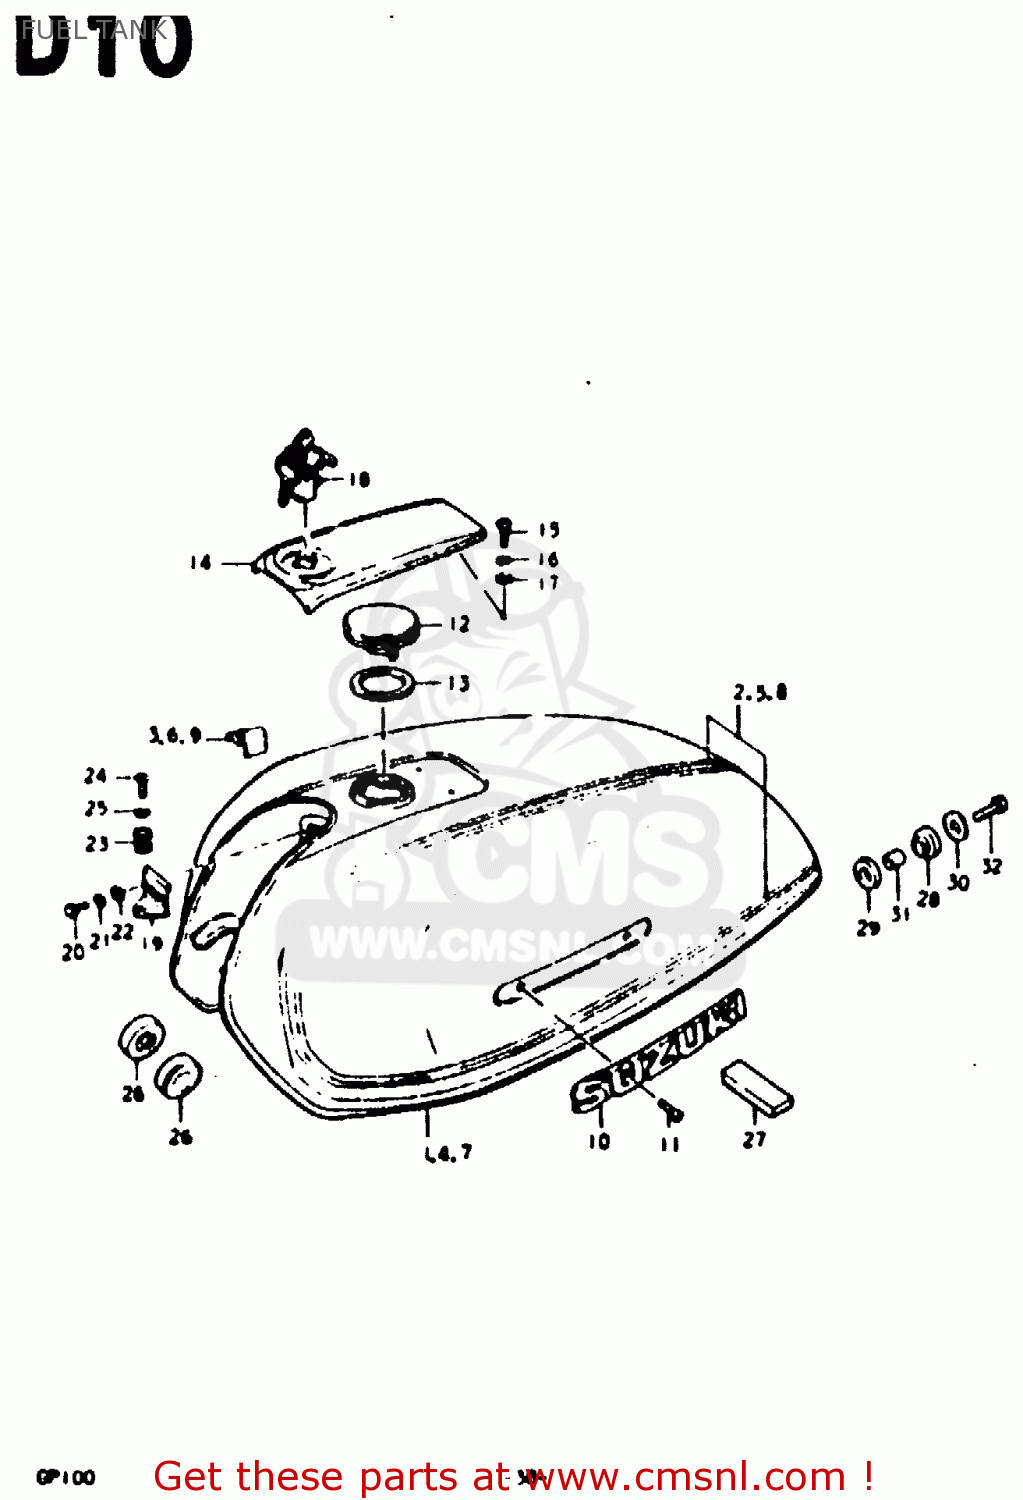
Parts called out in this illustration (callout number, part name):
1	TANK, FUEL
2	TAPE SET
3	CUSHION,FUEL TANK FR COVER
10	EMBLEM,FUEL TANK
11	SCREW 3X6
12	CAP,FUEL TANK
13	GASKET (NAS)
14	COVER,FUEL TANK FR
15	BOLT
16	LOCK WASHER
17	WASHER
18	LOCK,FUEL TANK FR COVER
19	HOLDER,FUEL TANK FRONT COVER
20	BOLT
21	LOCK WASHER
22	WASHER
23	SPRING
24	SCREW
25	LOCK WASHER
26	CUSHION
27	CUSHION
28	CUSHION
29	CUSHION
30	WASHER (8.5X29X1.6)
31	SPACER (8.2X12X17)
32	BOLT (8X30)
